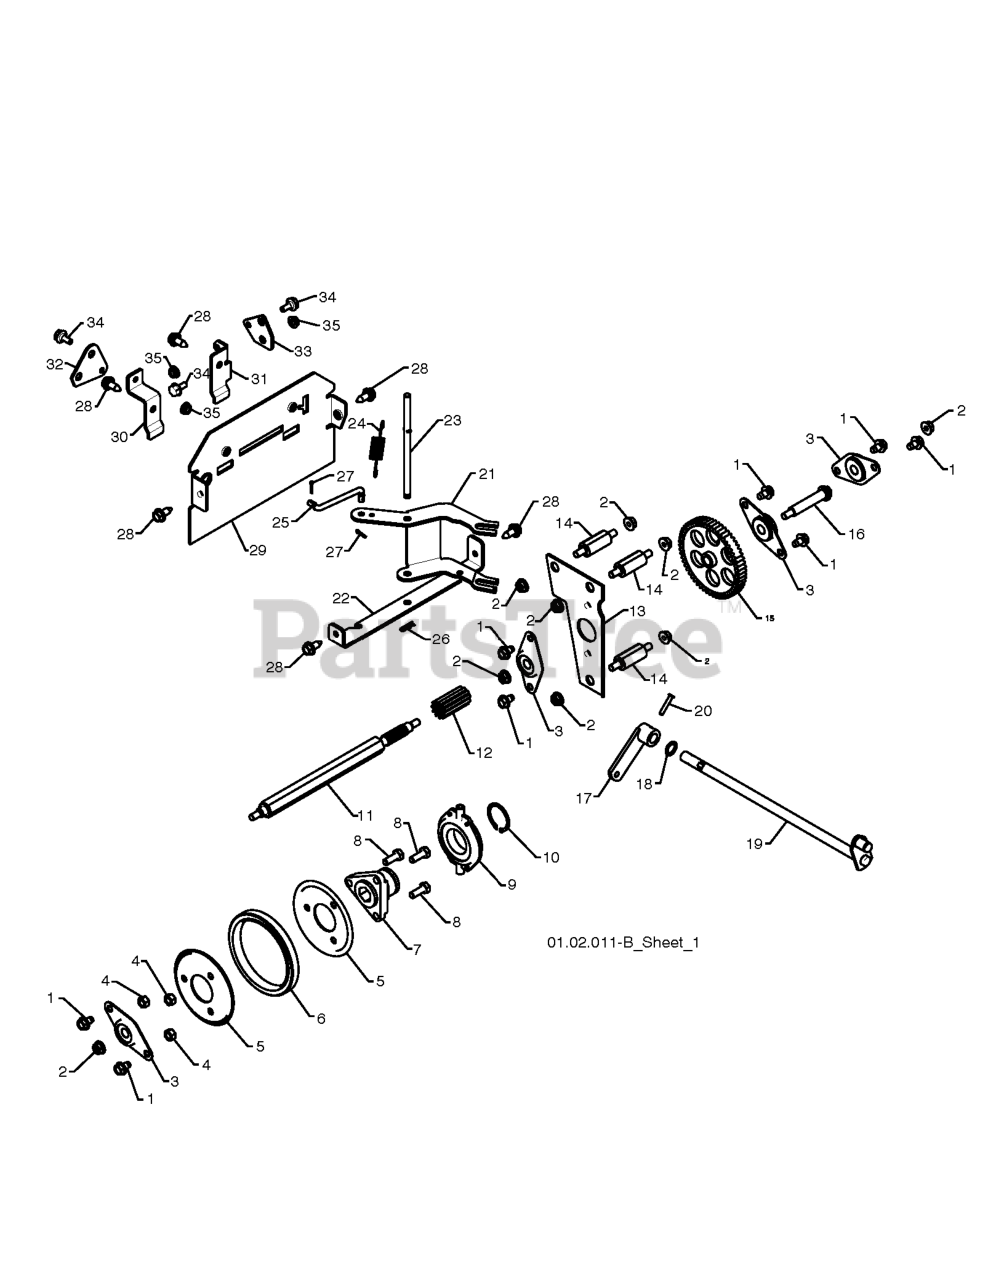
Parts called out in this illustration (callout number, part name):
1	Screw 5/16-18 x 1/2 Hex, Self Tapping 5/16-18 x 1/2
2	NUT.LOCK.5/16-18
3	BEARING, FLANGE
4	NUT.CENTERLOCK.5/16-
5	PLATE.RUBBER.WHEEL
6	RING, RUBBER WHEEL
7	HUB, RUBBER WHEEL
8	BOLT
9	TRUNNION BEARING ASSY
10	RETAINING RING (2 2)(3 2)
11	SHAFT.HEX.LONG
12	GEAR, PINION
13	AUXILLARY PLATE
14	SPACER, PLATE
15	GEAR, INTERMEDIATE
16	SHAFT, AUXILIARY
17	ARM, AUGER CONTROL
18	THRUST WASHER
19	CONTROL.SHAFT.ASM
20	CLEVIS PIN
21	LEVER, SPEED CONTROL
22	BRACKET, PIVOT, SHIFT
23	PIN, PIVOT
24	SPRING, BIAS
25	LINK, SPEED CONTROL
26	RETAINER CLIP PM
27	RETAINER CLIP
28	BOLT.HEX.HD.WASHER.5/16-18X.75
29	PLATE.REAR.SNOW.PNT.ORANGE
30	BRACKET.SHIFTER.PLATE.BZP
31	BRACKET.CLUTCH.PLATE.BZP
32	PLATE.SHIFTER.BZP
33	PLATE.CLUTCH.BZP
34	BOLT.SHOULDER.3/X.25
35	NUT.HEX.FLANGE.1/4
